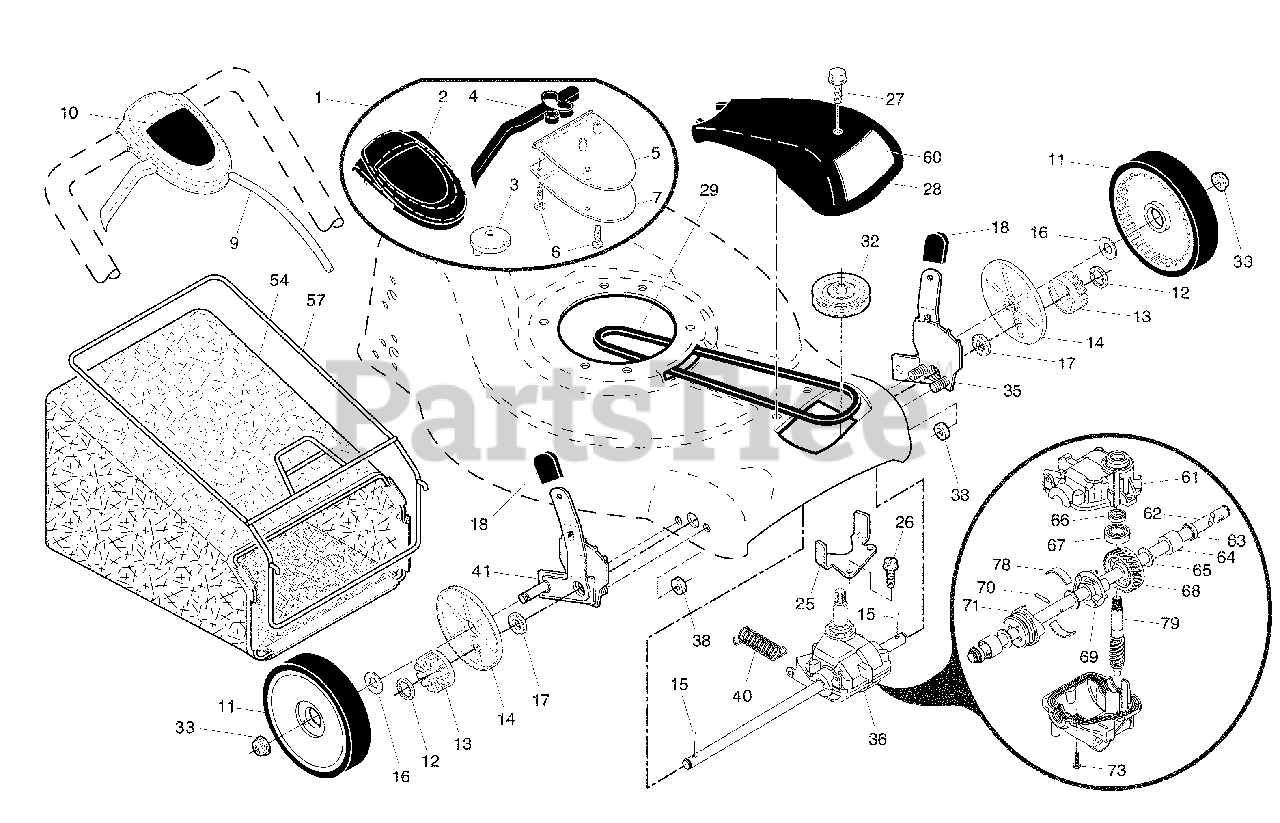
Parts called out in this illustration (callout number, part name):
1	Drive Control Assembly
2	Cover, Drive Control, Upper
3	Pulley
4	Lever, Drive Control
5	Cover, Drive Control, Lower
7	Mounting Bracket, Drive Control
9	Cable, Drive
10	Decal, Drive Control
11	Wheel & Tire Assembly
14	Dust Cover
15	Pawl, Drive
16	Washer 1/2 x 1-1/2 x .134
17	Bearing, Wheel Adjuster
18	Selector Knob
25	Belt Keeper
26	Screw, Hi-Lo Thread
27	Pan Head Tapping Screw #10-24 x 2-3/4
28	Drive Cover
32	Drive Pulley
33	Locknut, Hex
35	Kit, Wheel Adjuster, LH
36	Gearcase Assembly, Complete
38	Locknut, Hex 1/4-20
41	Kit, Wheel Adjuster, RH
54	Grassbag Assembly
57	Frame, Grassbag
60	Decal, Drive Cover
61	Case, Upper
62	Shaft, Output
63	Seal, Output Shaft
66	Seal, Worm Shaft
67	Bearing, Ball
68	Gear, 28 Teeth
69	Fixed Dog Clutch
70	Pin
71	Movable Dog Clutch
73	Screw, Case
74	Case, Lower
78	Spring, Leaf
79	Shaft, Worm
